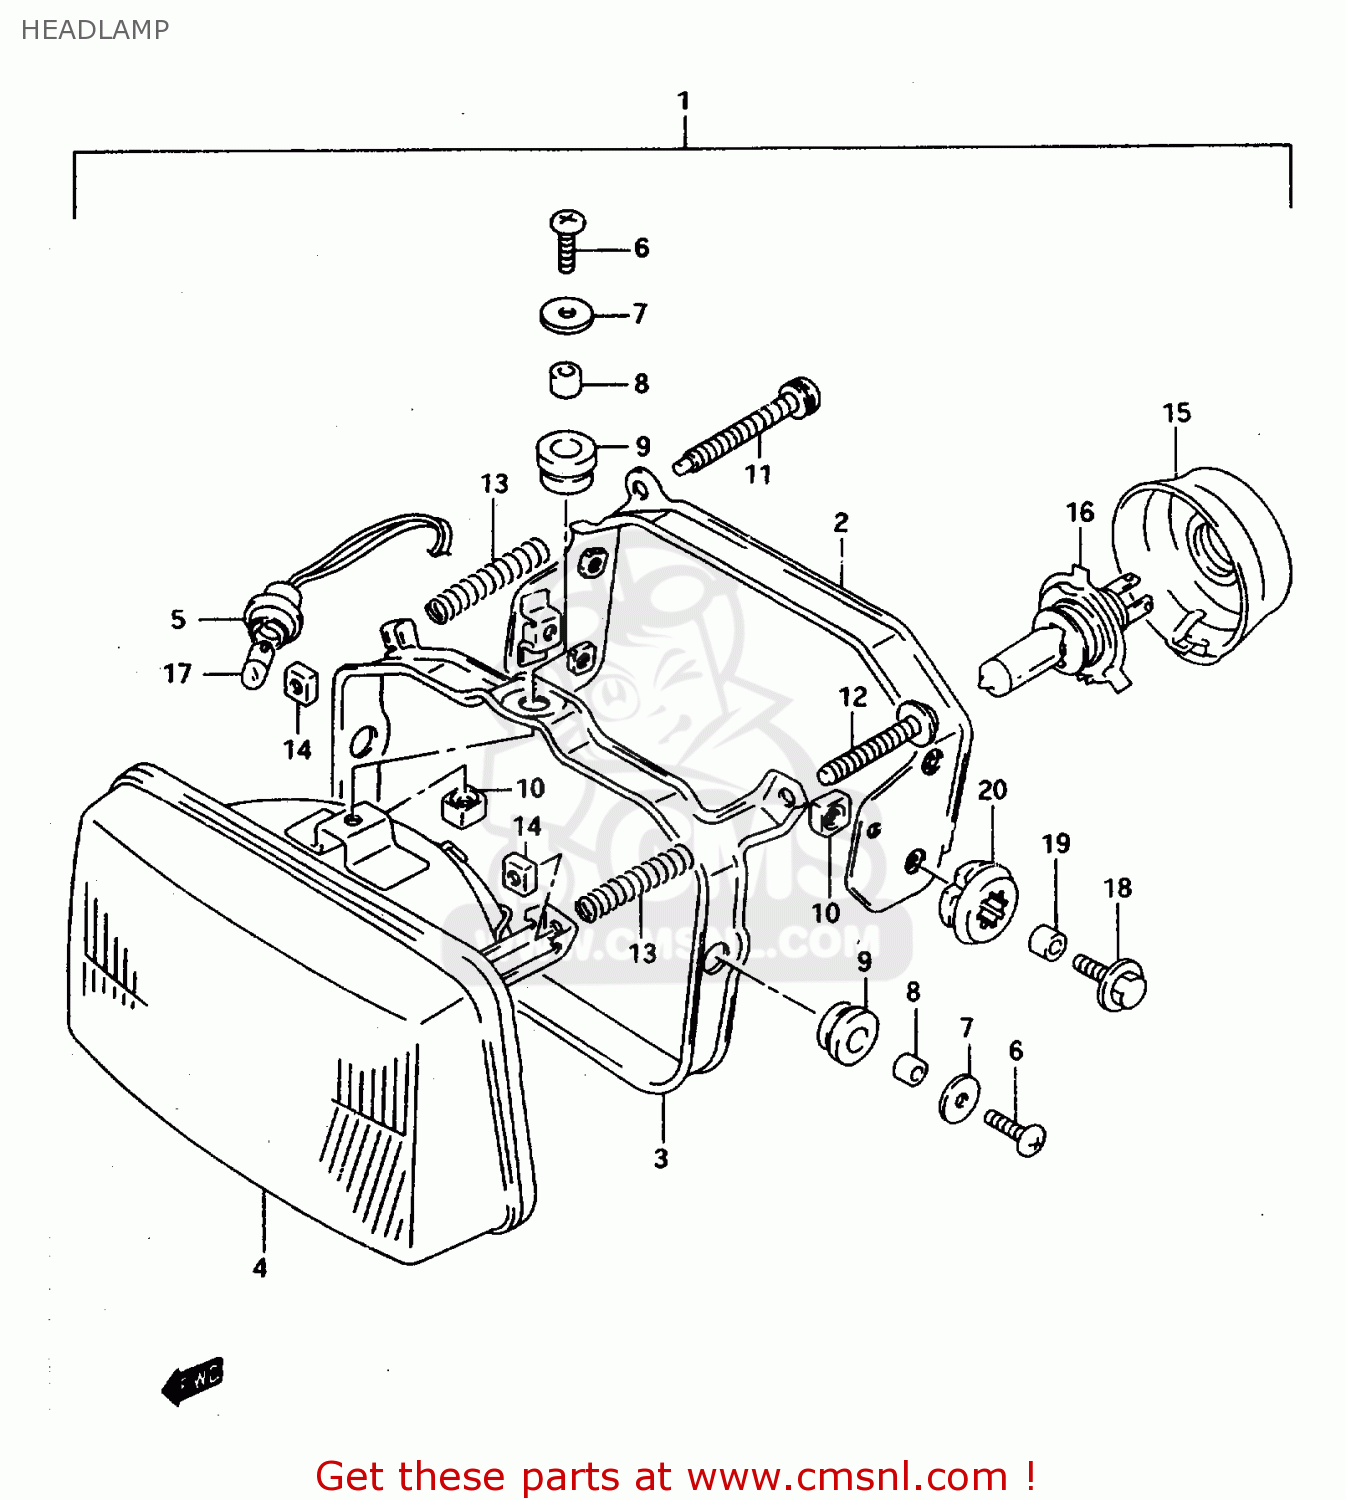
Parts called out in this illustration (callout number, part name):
1	HEADLAMP ASSY
2	HOUSING
3	RING
4	UNIT ASSY
5	SOCKET
6	SCREW
7	WASHER (5.5X18X1)
8	SPACER
9	CUSHION
10	NUT
11	SCREW, 5X45
12	SCREW
13	SPRING,ADJUSTER
14	NUT
15	COVER,SOCKET
16	BULB(12V60/55W,H4)
17	BULB(12V4W)
18	BOLT(6X20)
19	SPACER(6.5X10X10)
20	CUSHION
